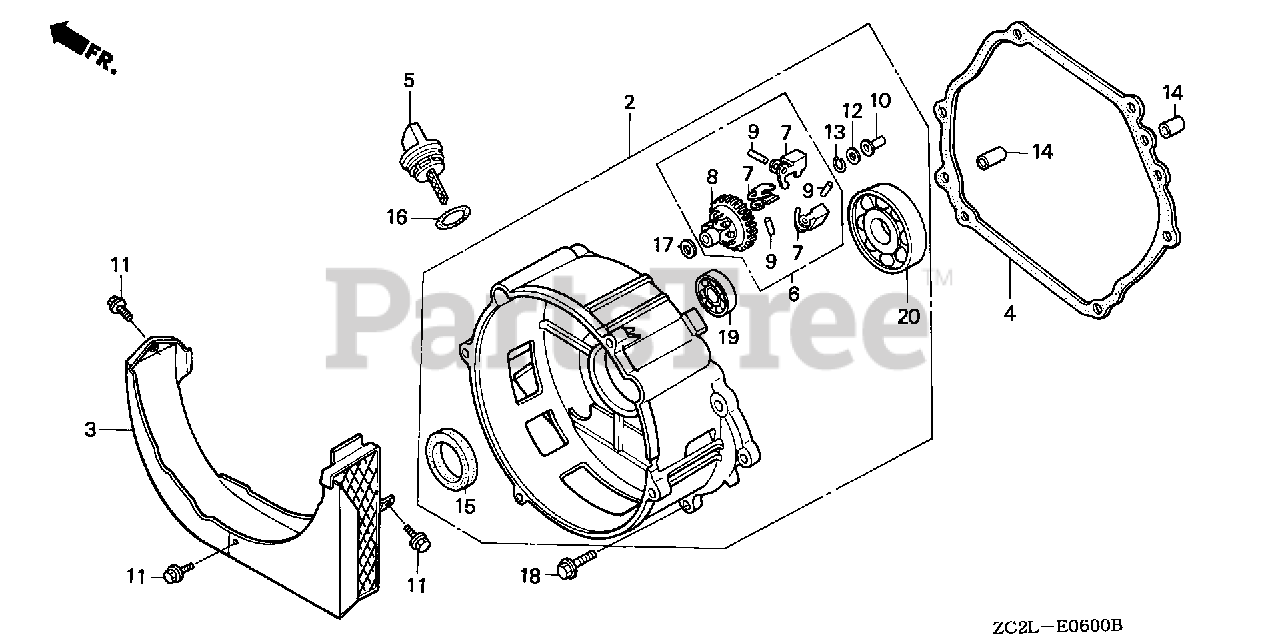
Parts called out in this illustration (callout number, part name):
2	COVER ASSY., CRANKCASE
3	COVER, DUCT
4	GASKET, CASE COVER
5	CAP, OIL FILLER
6	GOVERNOR ASSY.
7	WEIGHT, GOVERNOR
8	HOLDER, GOVERNOR WEIGHT
9	PIN, GOVERNOR WEIGHT
10	SLIDER, GOVERNOR
11	BOLT, FLANGE (5X10)
12	WASHER (6X16)
13	CLIP, GOVERNOR HOLDER
14	PIN, DOWEL (8X12)
15	OIL SEAL (35X52X8)
16	O-RING (26X2.7)
17	WASHER, PLAIN (6MM)
18	BOLT, FLANGE (8X40)
19	BEARING, RADIAL BALL (6202)
20	BEARING, RADIAL BALL (6207)
